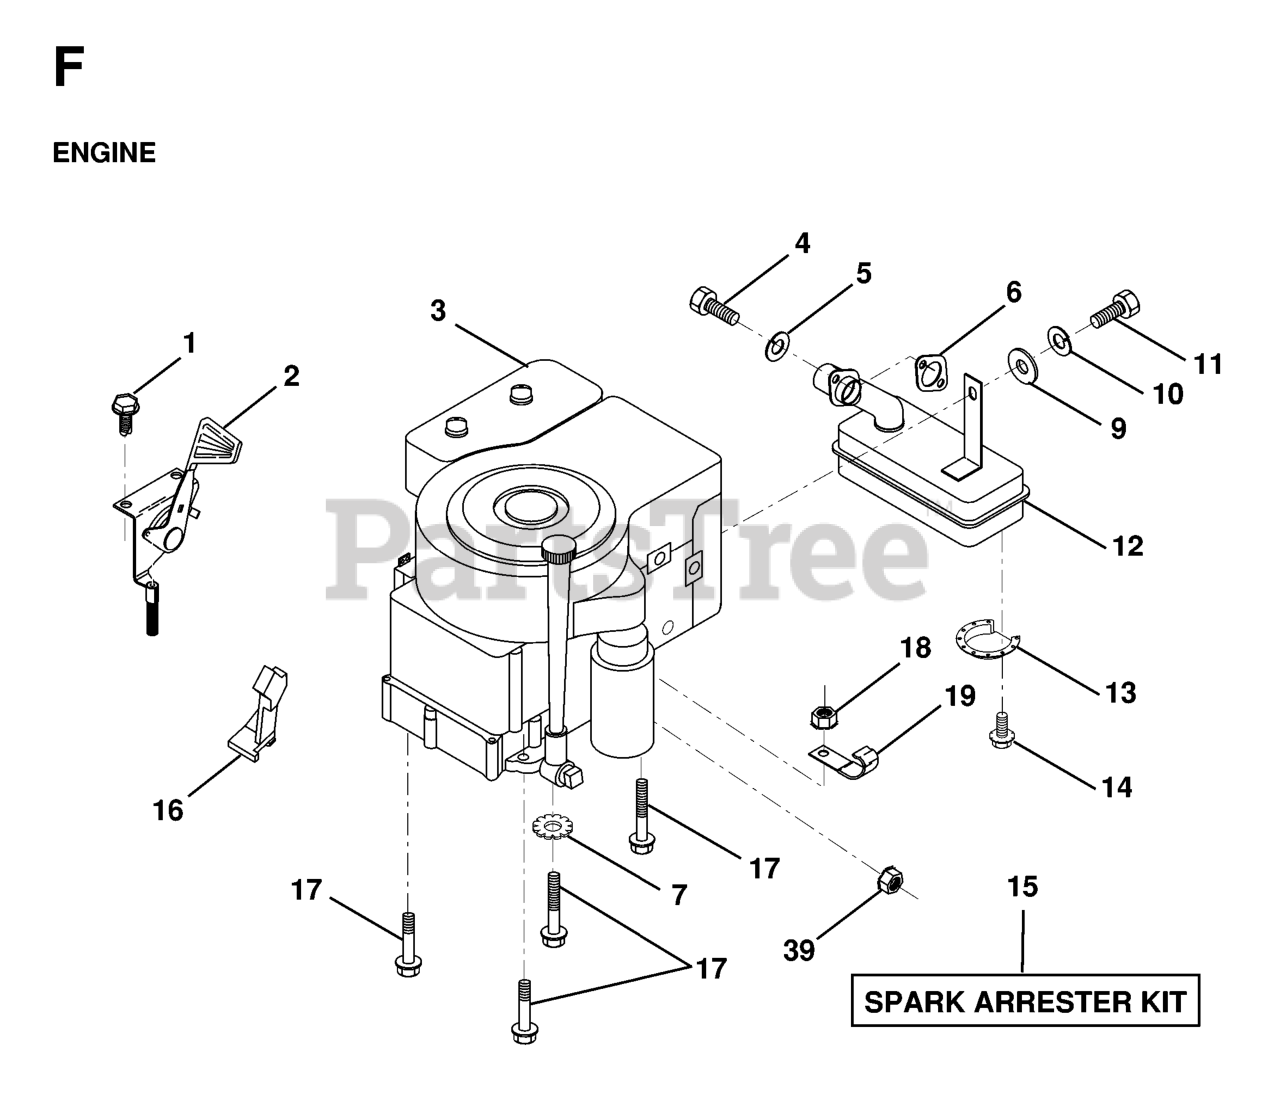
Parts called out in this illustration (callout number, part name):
2	CONTROL.TH/CH.RH.BLK.FLG.EEC
4	SCREW
5	WASHER.LOCK.HVY.HLCL.SPR.5/16
6	GASKET.ENG.1.313 ID.TIN PLATED
7	LOCKWASHER
9	WASHER
10	LOCKWASHER
12	MUFFLER.SINGLE.B&S.12HP
13	DEFL MUFFLER LTV
14	SCREW
15	KIT.SPARK ARRESTOR 794945 B&S
16	STOP THROTTLE
17	SCREW LT
19	CLIP T
39	NUT FLANGE 1/4-20 STARTER NUT
